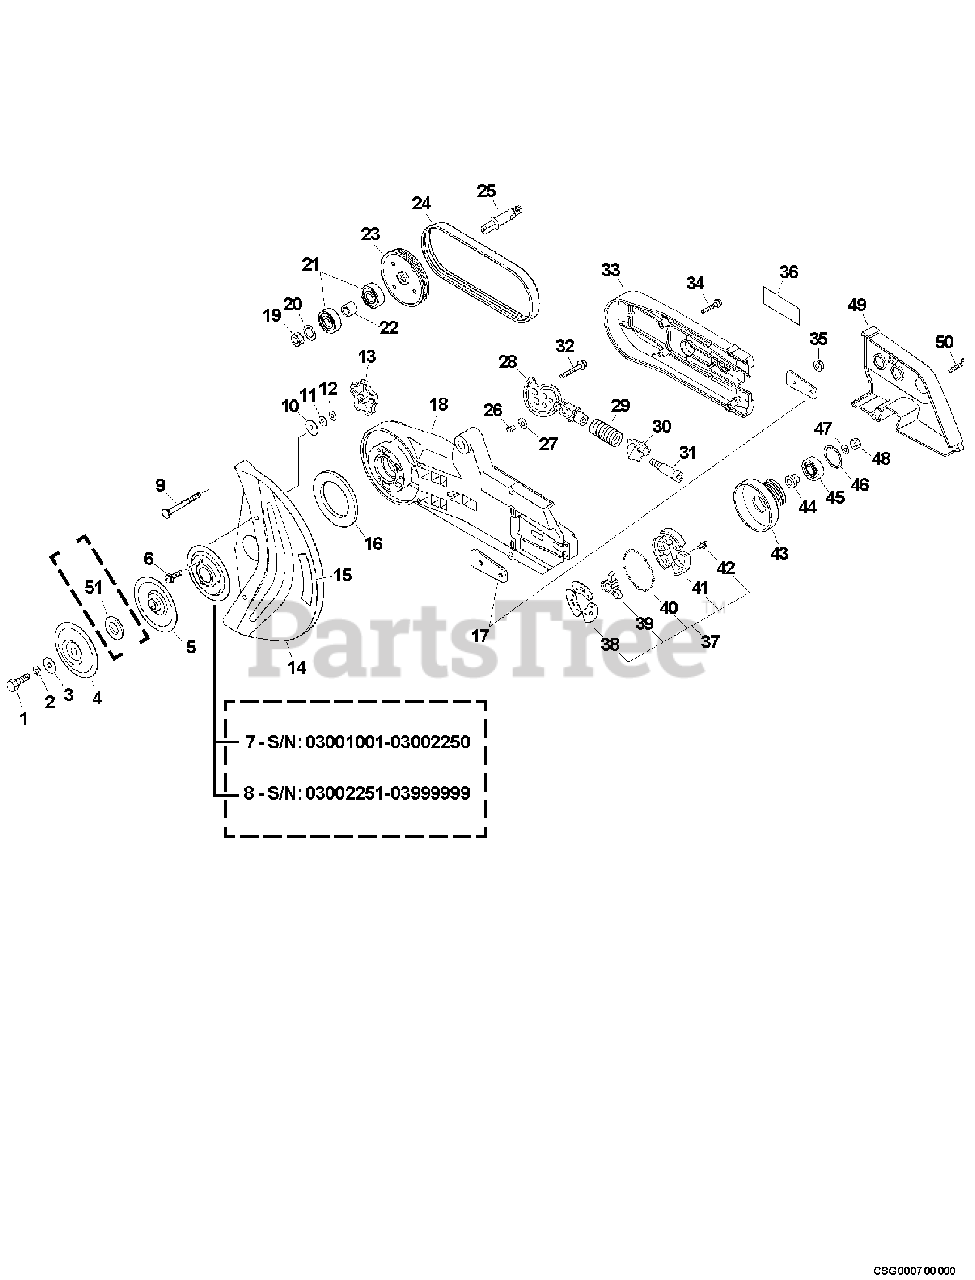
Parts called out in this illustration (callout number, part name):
1	BOLT - 10
2	LOCKWASHER - 10
4	FLANGE, CUTTER
5	FLANGE, CUTTER
6	SCREW - 4X10
7	PLATE, CUTTER COVER
8	PLATE, CUTTER COVER
9	BOLT - 8
10	WASHER - 8
11	WASHER - 8
12	LOCKWASHER - 8
13	KNOB, FASTENER
14	COVER, CUTTER
15	LABEL - CAUTION
17	SPACER, ARM
18	ARM, CUTTER
19	NUT - 10
20	WASHER - 10
21	BEARING, BALL - 6202
24	BELT
25	SHAFT, CUTTER
27	WASHER - SPRING
28	ADJUSTER
29	SPRING, ADJUST
30	HOLDER, SPRING
31	SCREW - 5
32	SCREW - 5X25
33	COVER, CUTTER ARM
34	SCREW - 5X25
35	NUT - FLANGE
36	LABEL - ECHO
37	CLUTCH ASSY
38	PLATE, CLUTCH
39	HUB, CLUTCH
40	SPRING, CLUTCH
41	CLUTCH SHOE SET
42	SCREW - 4X6
43	DRUM, CLUTCH
44	COLLAR - 10
45	BEARING, BALL - 6001 DDU
46	RING, RETAINING - 28
47	WASHER - 8
48	NUT - 8 -- LEFT HAND
49	COVER, V-BELT
50	SCREW - 5X25
51	WHEEL ADAPTER - 25mm
